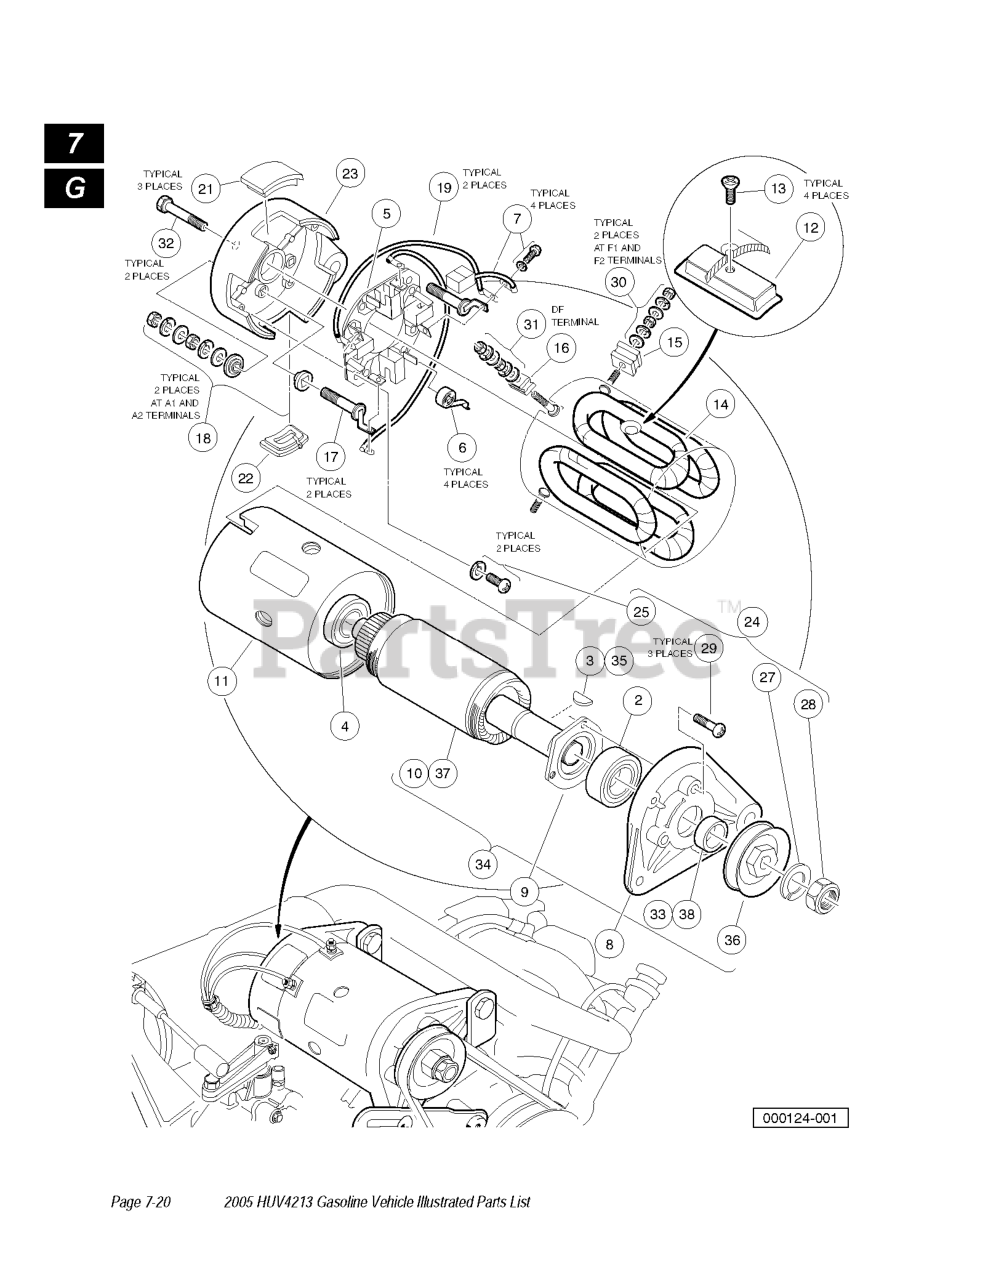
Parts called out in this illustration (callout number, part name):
1	STARTER-GENERATOR (CW)
3	KEY, STARTER GENERATOR
4	BEARING, COMMUTATOR BALL
5	BRUSH HOLDER ASSEMBLY (CW)
6	BRUSH SPRING SET
7	BRUSH & SCREW SET (CW)
8	FRONT BRACKET
11	FIELD COIL HOUSING
14	FIELD STATOR COIL ASSEMBLY
15	F INSULATOR SET
16	DF INSULATOR
17	A CONNECTOR (CW)
18	SCREW & MOLD ASSEMBLY SET
19	BRUSH CONNECTOR ASSEMBLY (CW)
23	REAR BRACKET (CW)
24	NUT & SCREW SET
25	BRUSH HOLDER ASM SCREW
30	NUT & WASHER SET
31	NUT & WASHER SET
32	THROUGH BOLT SET
34	Armature Asm Conversion Kit
35	KEY, STARTER GENERATOR
36	PULLEY, STARTER GENERATOR
